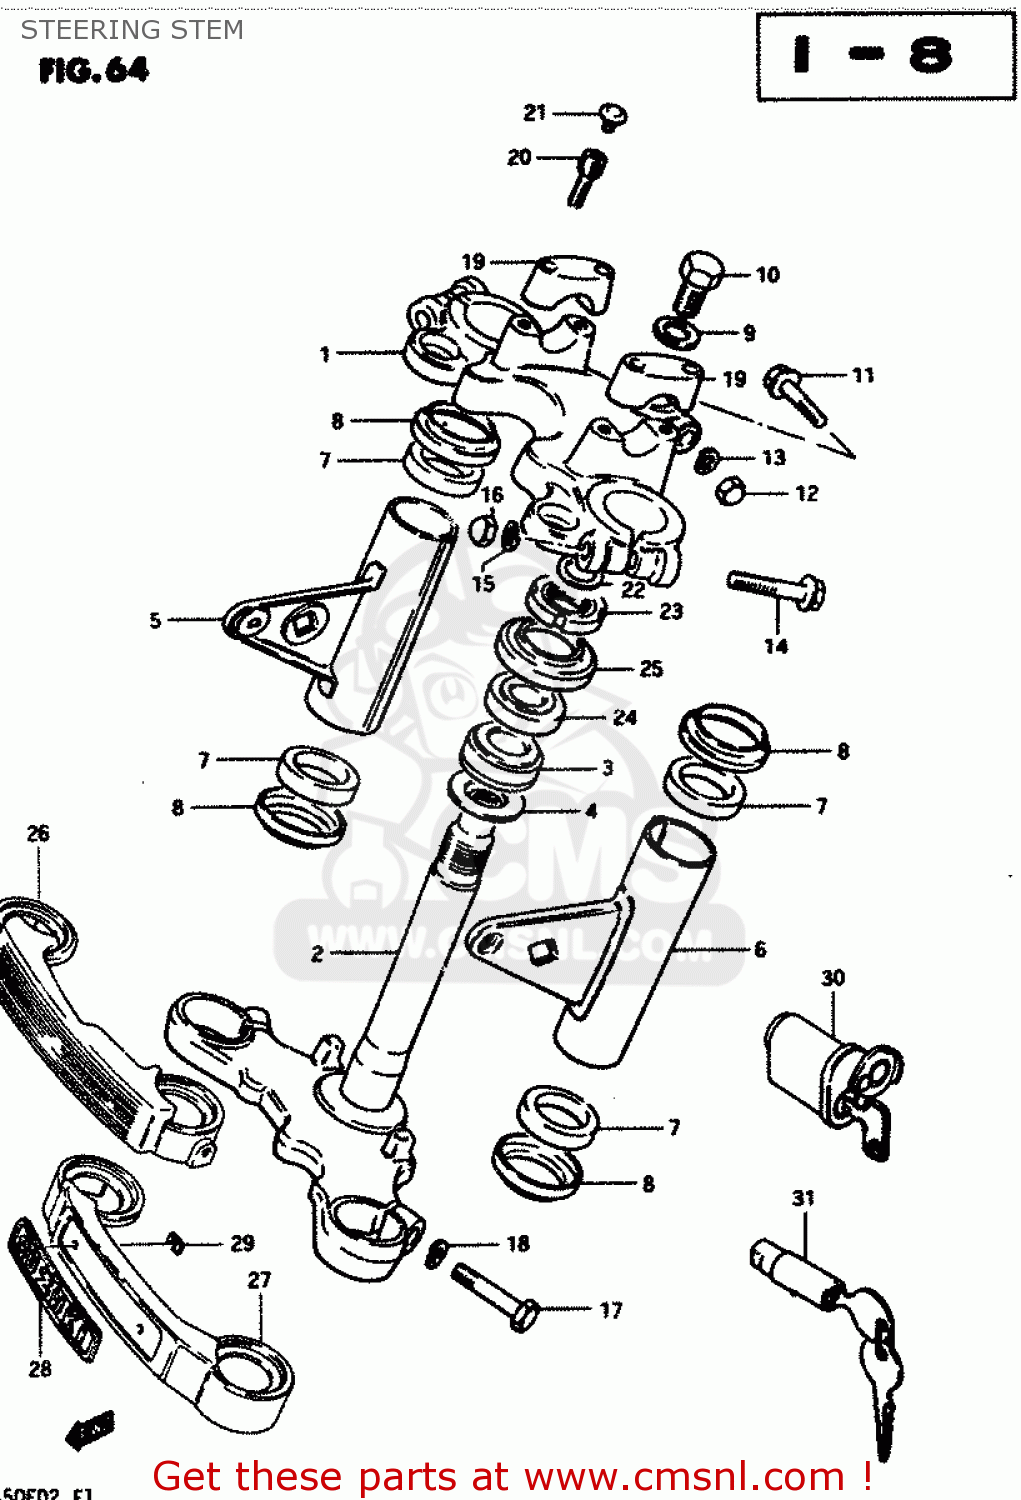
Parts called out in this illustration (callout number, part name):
1	HEAD,STEERING STEM
2	STEM,STEERING
3	BEARING
4	WASHER,THRUST
5	BRACKET,HEADLAMP,RIGHT
6	BRACKET,HEADLAMP,LEFT
7	CUSHION,HEADLAMP BRACKET
8	CAP,HEADLAMP BRACKET
9	WASHER (12.5X26X1.6)
10	BOLT(12X20)
11	BOLT, UPPER
12	NUT,M8X1.25X12
13	LOCK WASHER
14	BOLT
15	LOCK WASHER
16	NUT
17	BOLT
18	LOCK WASHER
19	HOLDER,HANDLEBAR(BLACK)
20	BOLT
21	CAP(OD:14.5)
22	WASHER(18.5X24X1)
23	NUT,STEERING STEM
24	BEARING, UPPER
25	DUST SEAL,STEERING UPR
26	COVER,FRONT FORK
27	COVER,FRONT FORK
28	EMBLEM,FR FORK COVER
29	NUT
30	LOCK ASSY, STEERING (NEIMAN TYPE EXECUTE
31	LOCK ASSEMBLY,STEERING (NEI
